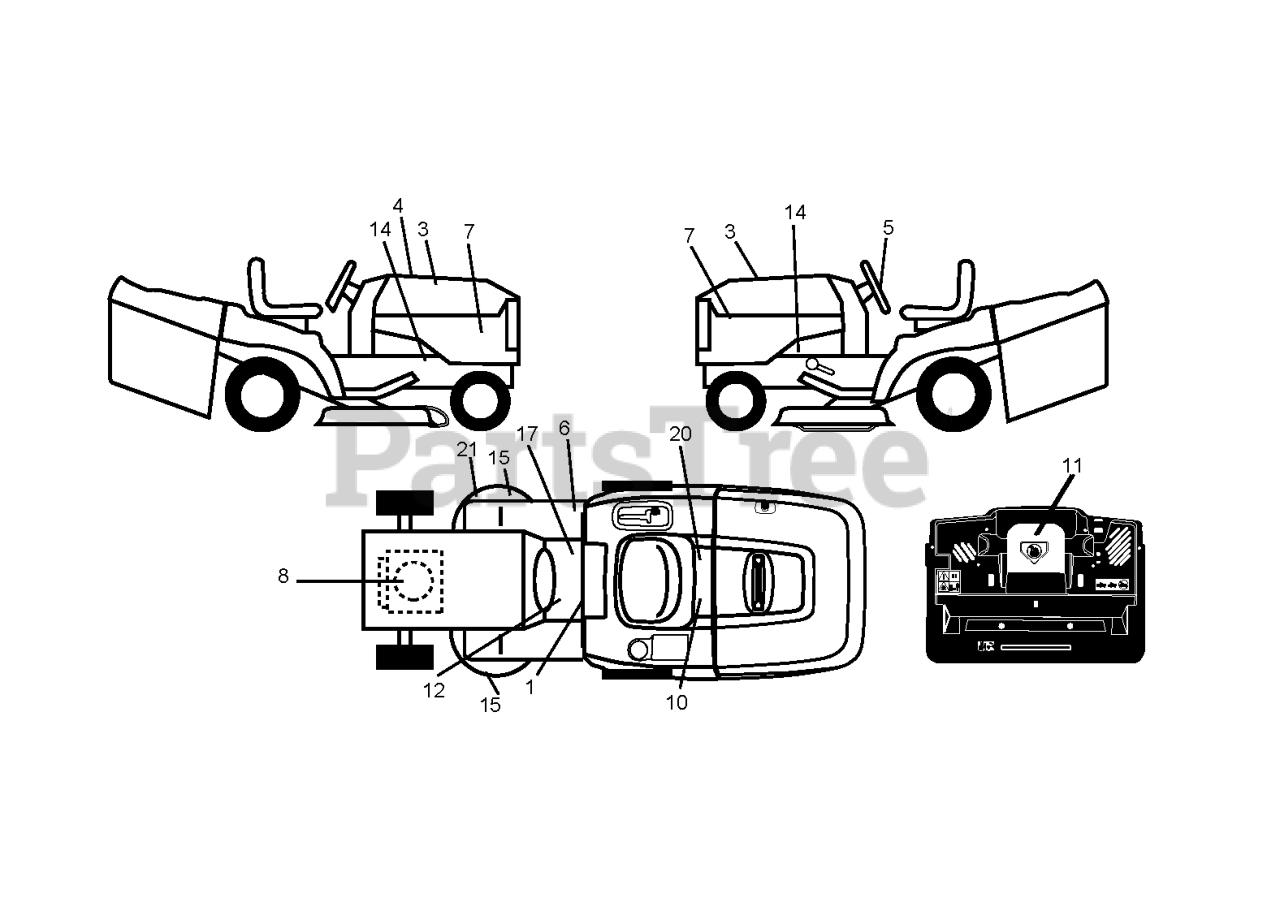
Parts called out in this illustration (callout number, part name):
1	LABEL
3	DECAL.HOOD.NAMELOGO.HUSQ
5	DECAL.WHEEL.STRG.LGN.H
6	Decal, Fender 100 DB/CE
8	DECAL
10	DECAL BTRY SYMBOLS
11	DECAL.INTERNATIONL.CUTFINGER
12	DECAL
17	DECAL PARK BRAKE
20	DECAL.BYPASS.FENDER.CRD.LT.YT
